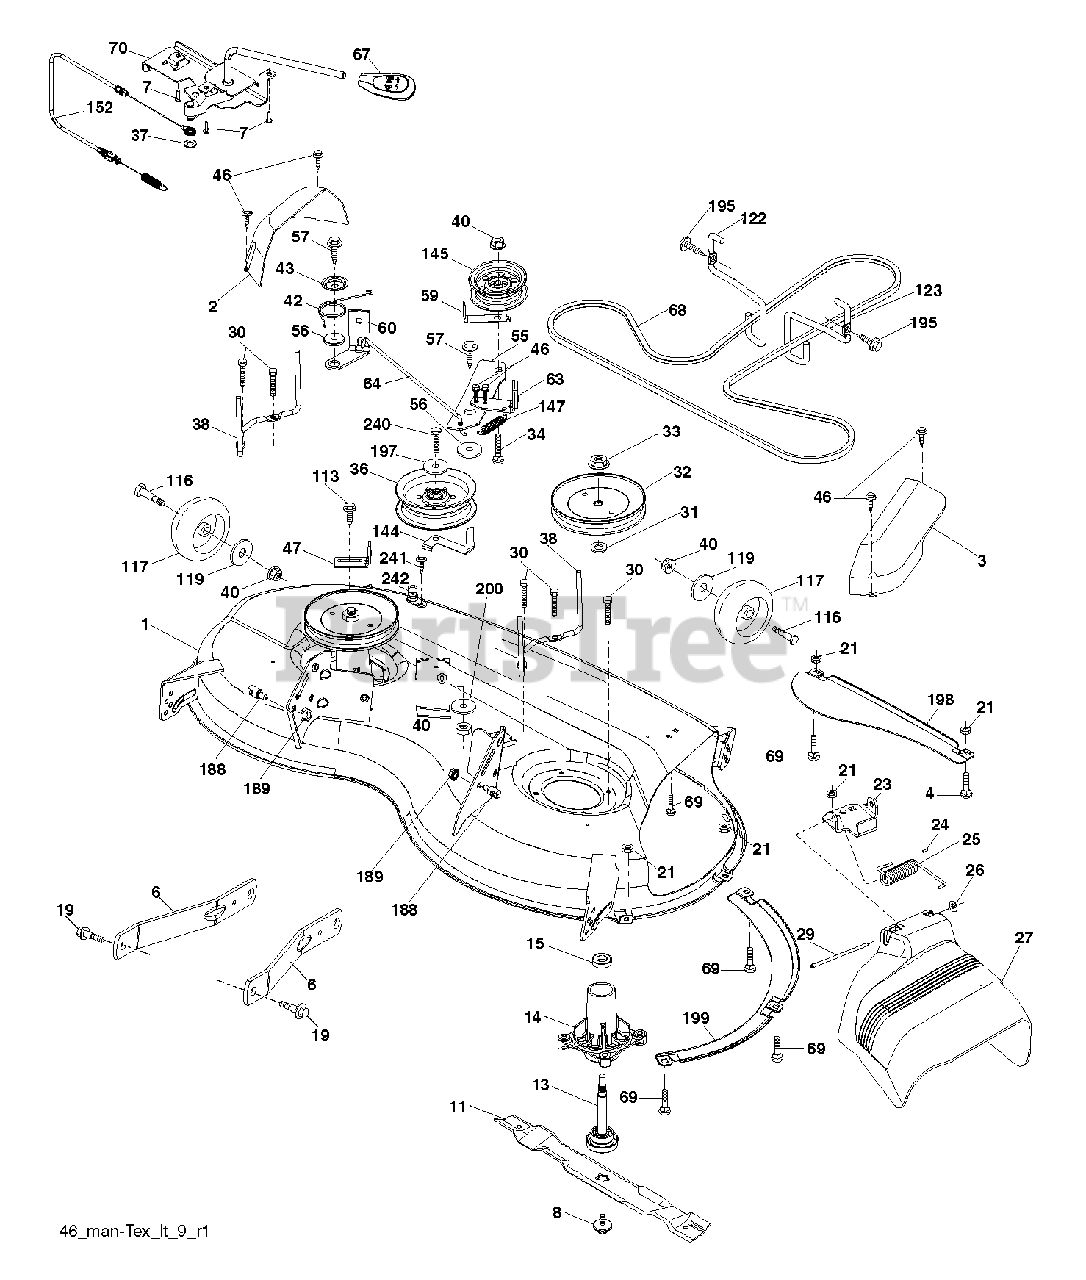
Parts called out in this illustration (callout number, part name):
1	DECK.SVC.46"441616X431
2	COVER.MANDREL.LH.46"
3	COVER.MANDREL.RH.46"
4	BOLT
6	ARM.SUSPENSION.MOWER.R
7	SCREW.#10 X 0.750.BOS (2 2)
8	BOLT.WASHER.ASM.7/16-2
11	BLADE.MOWER.46".HI.LIFT
13	SHAFT.ASM.MDRL.N/GREASE.38
14	HOUSING.MANDREL.4PT.
19	BOLT.SHOULDER
21	LOCKNUT
23	BRKT.DEFLECTOR.38"2005+
24	CAP-SLEEVE LT
25	SPRING.TORSION.DEFLECT
26	NUT PUSH M
27	SHIELD.DEFLECTOR.MOWER.46"BLAC
29	ROD.HINGE
30	SCREW, WASHER HEAD
31	WASHER.SPACER.MANDREL
32	PULLEY.MANDREL.5.438.PD
33	NUT.FLANGE.LOCK.TOP
34	BOLT.3/8-16X1.50
36	PULLEY.IDLER.2006
38	KEEPER.BELT.MANDREL.PULLEY
40	NUT LOCK FLG 3/8-16 UNC
42	SPRING.TORSION.BRAKE
43	SRPING.TORSION.RETAINE
46	SCREW.1/4-20X5/8
47	BRKT.CLUTCH.CABLE
55	IDLER.ARM
56	SPACER.RETAINER
57	SCREW 3/8-16X1
59	GUARD, BELT
60	ARM BRAKE MOWER RH 38"
64	LINKAGE BRAKE
67	HANDLE.CLUTCH.CABLE.LT
68	V-BELT
69	BOLT
70	CLUTCH.ASM.MANUAL.LT.TEX
113	BOLT.5/16HEX.WHS.HD
116	BOLT M
117	WHEEL.GAGE.HALF.SPOKED
119	WASHER
122	KEEPER BELT ENGINE LH
123	KEEPER BELT RH
144	KEEPER.BELT.MOWER
145	PULLEY.IDLER.48"PRIMARY
147	SPRING RETURN
152	CABLE.MECHANICAL.CLUTCH
188	STUD.FASTNER.W/ANTI-ROTATE
189	NUT LOCK HEX FLANGE 5/16-18
195	SCREW, 3/8-16X3/4
197	WASHER
198	BAFFLE CENTER FRONT
199	BAFFLE FRONT RH
200	WASHER.13/32 X 1 X 1/2.11GUARD
240	BOLT-HEX EAK
241	SCREW.TT.#10-32X.5.3/8.FLANGE
242	PORT.WASHOUT
